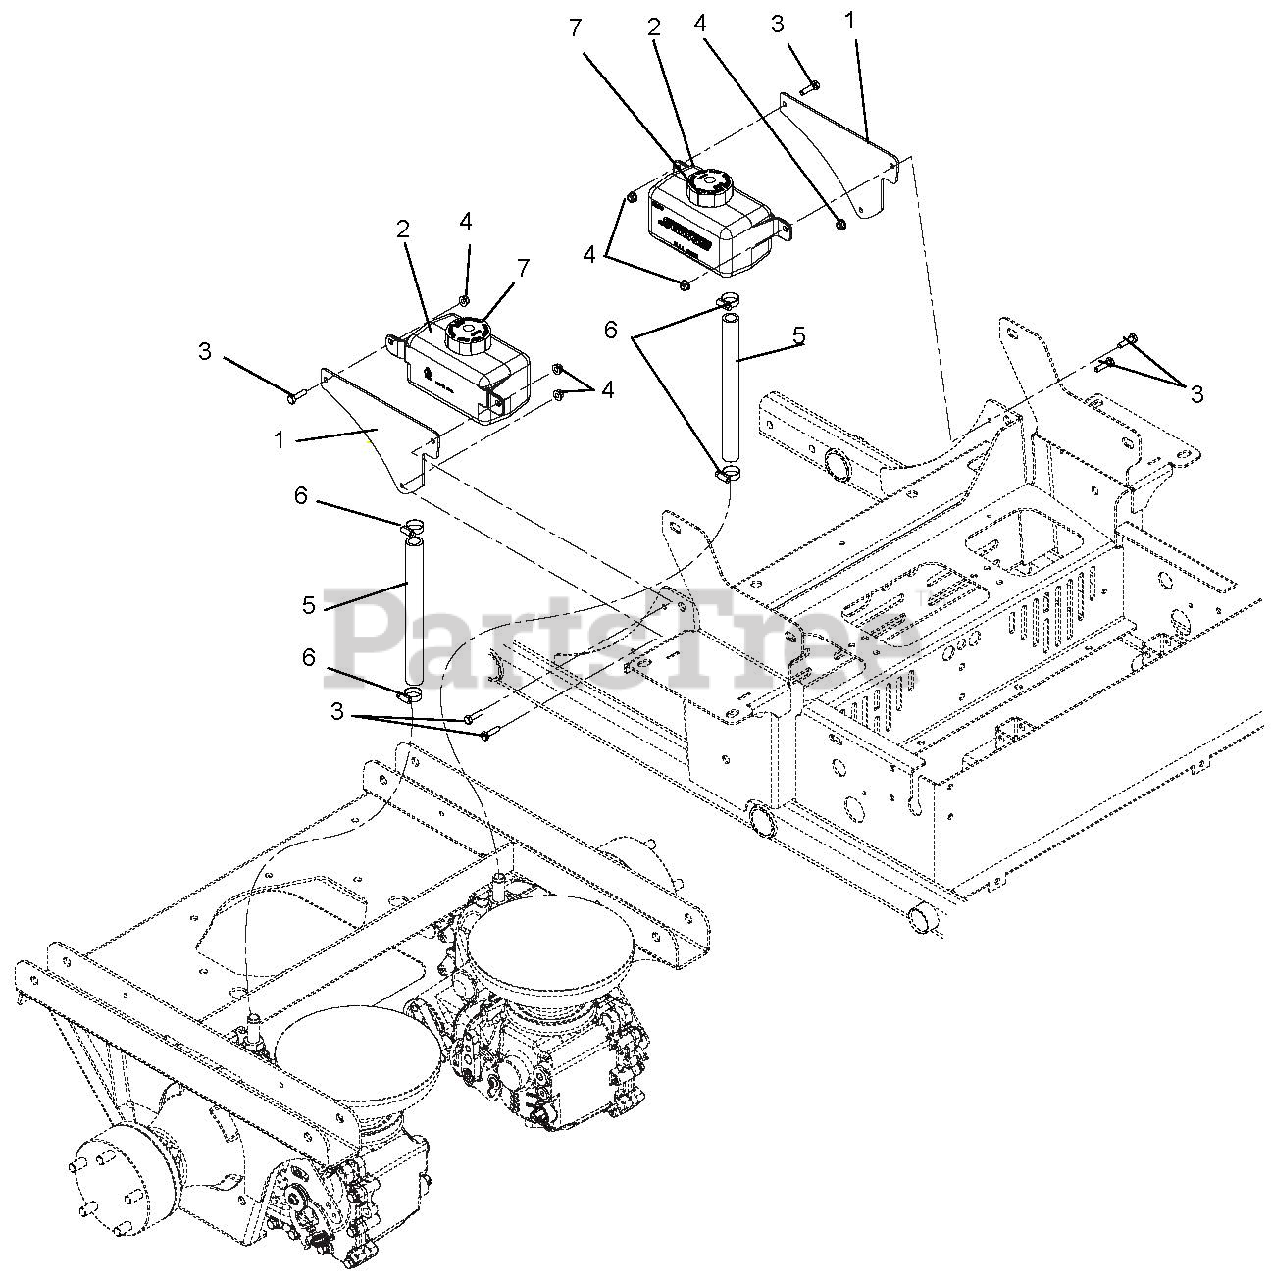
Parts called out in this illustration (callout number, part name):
1	Plate, Hydro Overflow Tank Mounting
2	Tank, Hydraulic 1000ML
3	Bolt, Hex .25-20 x 1.00 GR5 YWZC
4	Nut, Locking Nylon Flange .25-20 YWZC
5	Hose, Hydro Overflow
6	Clamp, .88 DIA. Hose
7	Cap, Hydro Reservoir REPLAC.
